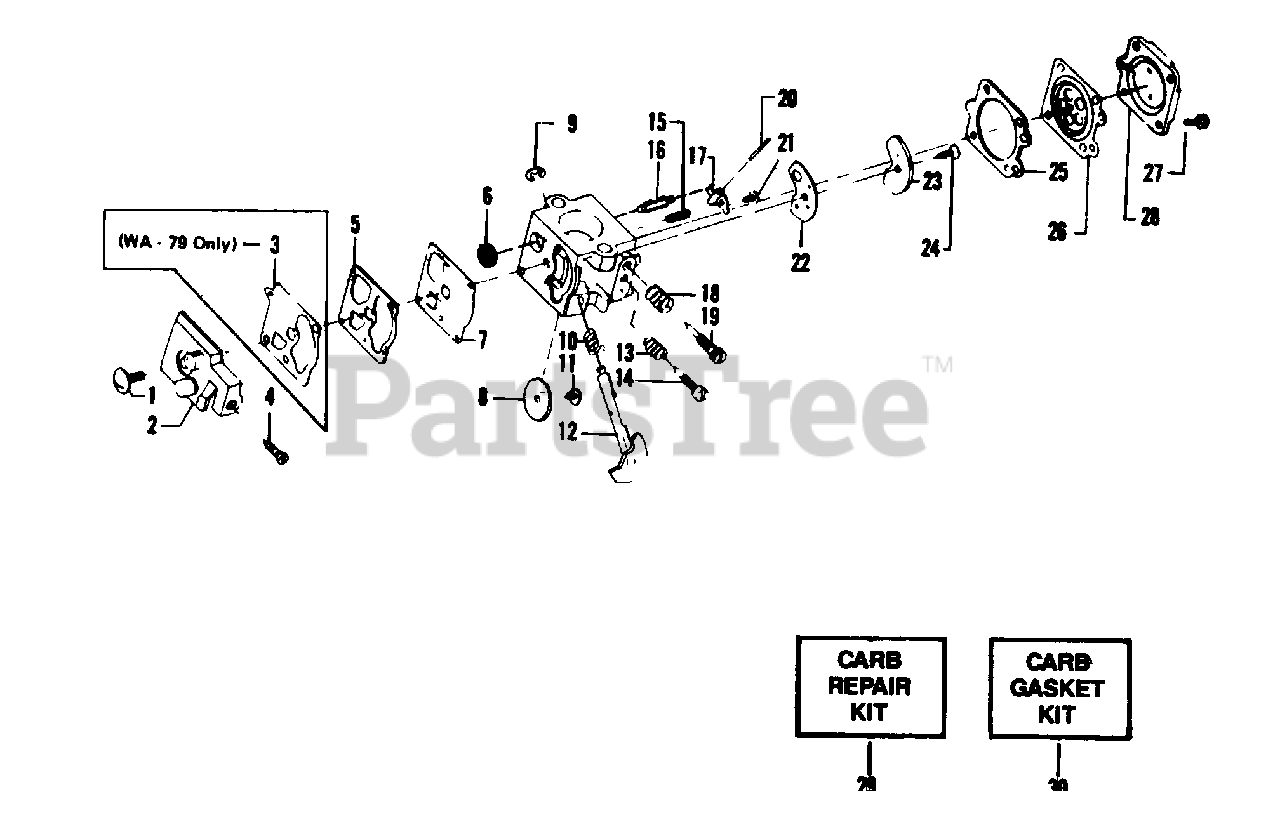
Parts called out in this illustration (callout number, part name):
1	Screw - Pump Cover
2	WA-149 (#35183)
3	Diaphragm - Pump (WA-79 Only)
4	Screw - Idle Adjustment
5	Gasket - Pump
5	WA-149 (#35183)
6	Screen Inlet
7	Diaphragm - Pump
7	WA-149 (#35183)
8	Valve - Throttle
9	Clip - Throttle Shaft
10	Spring - Throttle Return
11	Screw - Throttle Valve
12	Shaft Assembly - Throttle
13	Spring - Idle Needle
14	Needle - Idle
15	Spring - Metering Lever
16	Valve - Inlet Needle
17	Lever - Metering
18	Spring - Hi Speed Needle
19	Needle - Hi Speed
20	Pin - Metering Lever
21	Screw - Metering Lever Pin
22	Gasket - Circuit Plate
23	Plate - Circuit
24	Screw - Circuit Plate
25	Gasket - Metering Diaphragm
26	Diaphragm Ass'y - Metering
27	Screw Ass'y - Metering Cover & Throttle Shaft Clip
28	Cover - Metering Diaphragm
29	Kit - Carb Kwik Repair
29	WA-149 (#35183)
30	Kit-Carb Gasket/Diaphragm
30	WA-149 (#35183)
